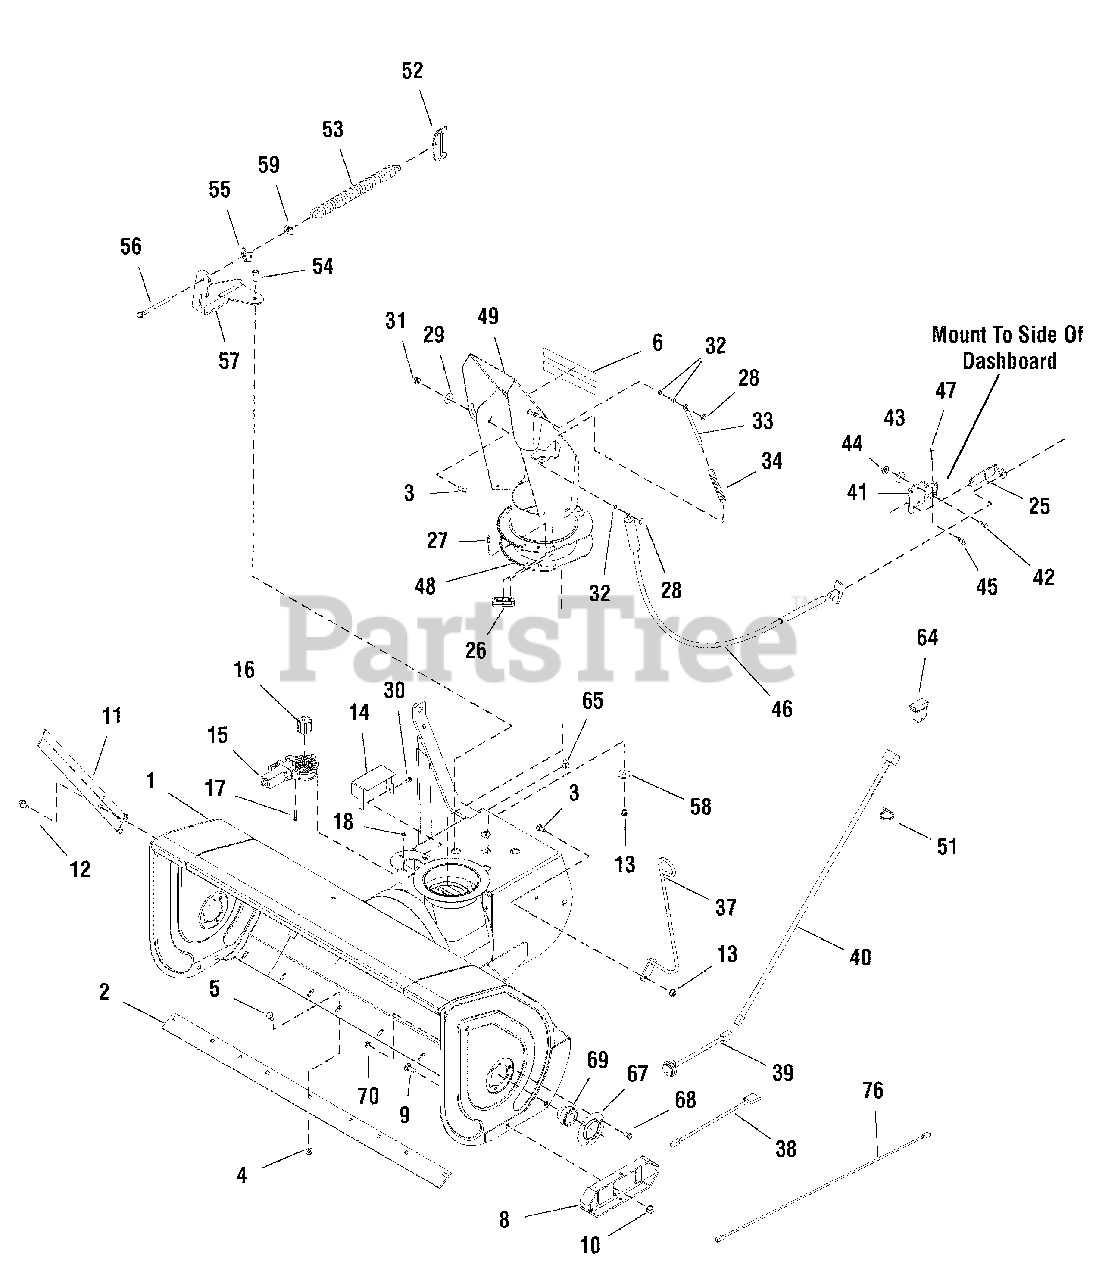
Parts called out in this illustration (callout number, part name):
1	AUGER HOUSING ASSEMBLY, 42"
2	SCRAPER BAR, 42"
3	BOLT, Carriage, 5/16 - 18 x 3/4
4	LOCKNUT, Flange, 5/16 - 18
5	BOLT, 5/16-18 x 5/8
6	DECAL, Black Strip
8	SKID SHOE, Black
9	BOLT, Carriage, 3/8 - 16 x 1
10	NUT, ESNA Flange, 3/8 - 16
11	DRIFT CUTTERS, Black
12	SCREW, Hex Washer Head Taptite, 5/16 - 18 x 3/4
13	NUT, Keps Washer, 5/16 - 18
14	COVER, Gear, Black
15	MOTOR, Electric
16	GEAR, Pinion
17	SCREW, Hex Washer, #10 - 24 x 1-1/4
18	NUT, Hex Keps, #10 - 24
25	BRACKET, Cable
26	CHUTE RETAINERS
27	SCREW, Plastite
28	NUT, Push, 1/4
29	WASHER, Nylon
30	SCREW, Hex Washer Head Taptite, 1/4 - 20 x 3/8
31	NUT, Hex Flange ESNA, 5/16 - 18
33	ROD, Spring
34	SPRING, Compression
37	GUIDE ASSEMBLY, Cable
38	HARNESS, Spout Rotator
39	HARNESS, Power Outlet
40	HARNESS ASSEMBLY, Chute
41	BRACKET, Cable Mount
42	CAPSCREW, 1/4 - 20 x 7/8
43	WASHER, Special
44	NUT, Hex Keps, 1/4 - 20
45	HAIRPIN, 1/16
46	CABLE ASSEMBLY
47	PIN, Flat Head
48	GEAR, Chute
49	CHUTE ASSEMBLY
51	CABLE TIE
52	SPRING ANCHOR
54	CAPSCREW, 5/16 - 18 x 1
55	RETAINER, Spring
56	CAPSCREW, 5/16 - 18 x 4-1/2
57	SPRING ANCHOR ASSEMBLY
59	NUT, Pushpal, 5/16 - 18
64	SWITCH, Chute Control
67	Flange, Bearing
68	CAPSCREW, 5/16 - 18 x 5/8
69	BALL BEARING
70	NUT, Hex, Flange, 5/16 - 18
76	HARNESS, Chute
